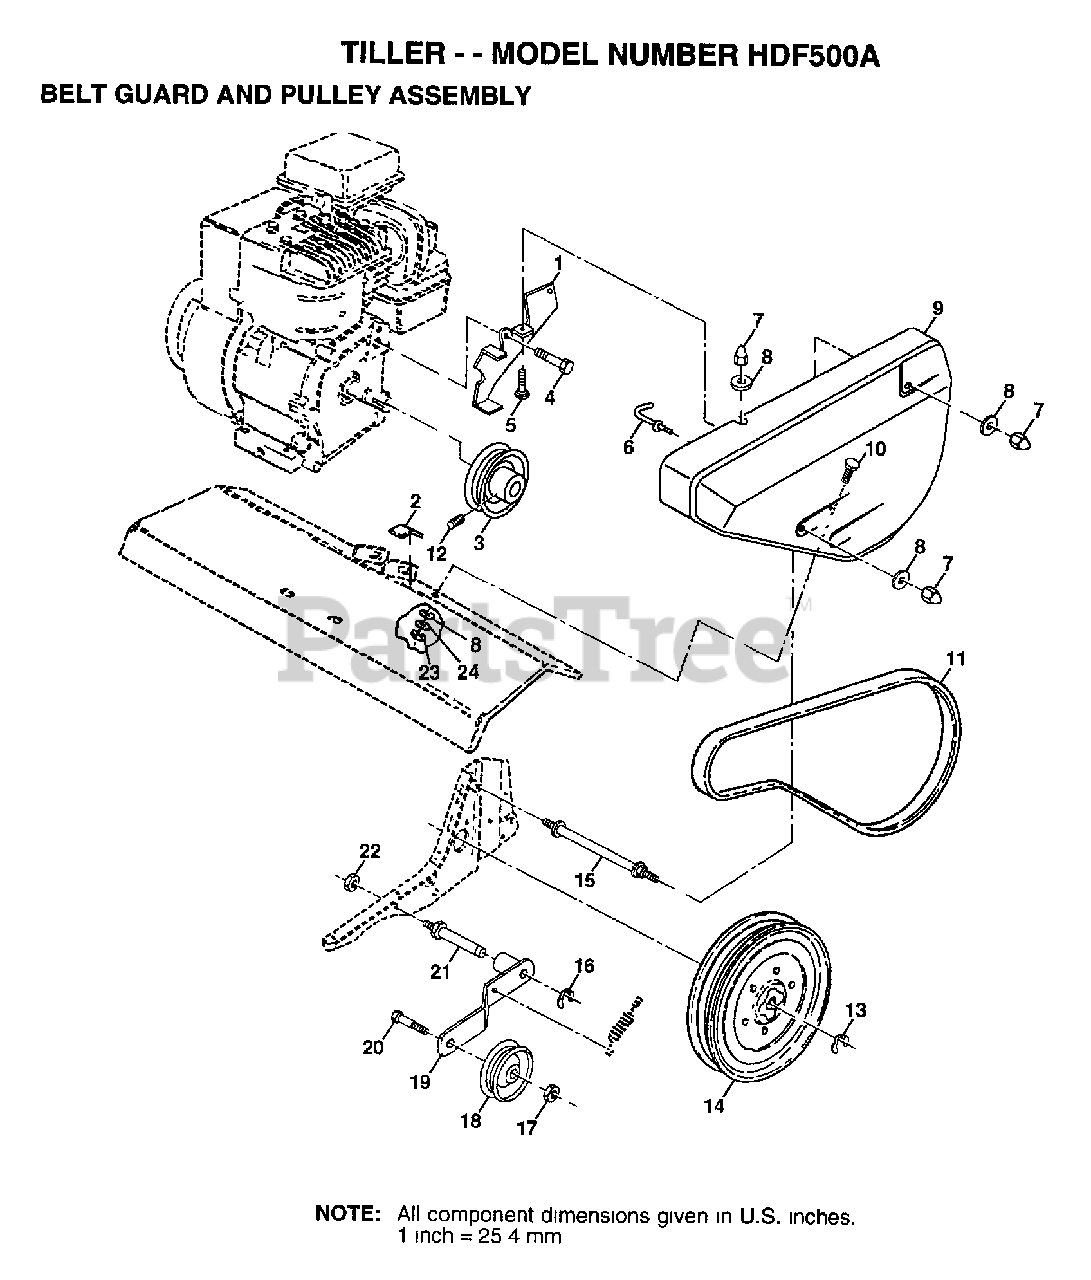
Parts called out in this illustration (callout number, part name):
2	PAD IDLER TI
3	ENGINE PULLEY
5	BOLT
7	NUT-CAP TI
8	WASHER
9	GUARD.PNT.BELT
10	BOLT T
11	V BELT STD
12	SET SCREW
14	SHEAVE.TRANS
15	BOLT TI
16	KLIP RING TI
17	NUT
19	IDLER ARM TI
21	SHAFT IDLER TI
22	JAM NUT TI
24	LOCKWASHER
